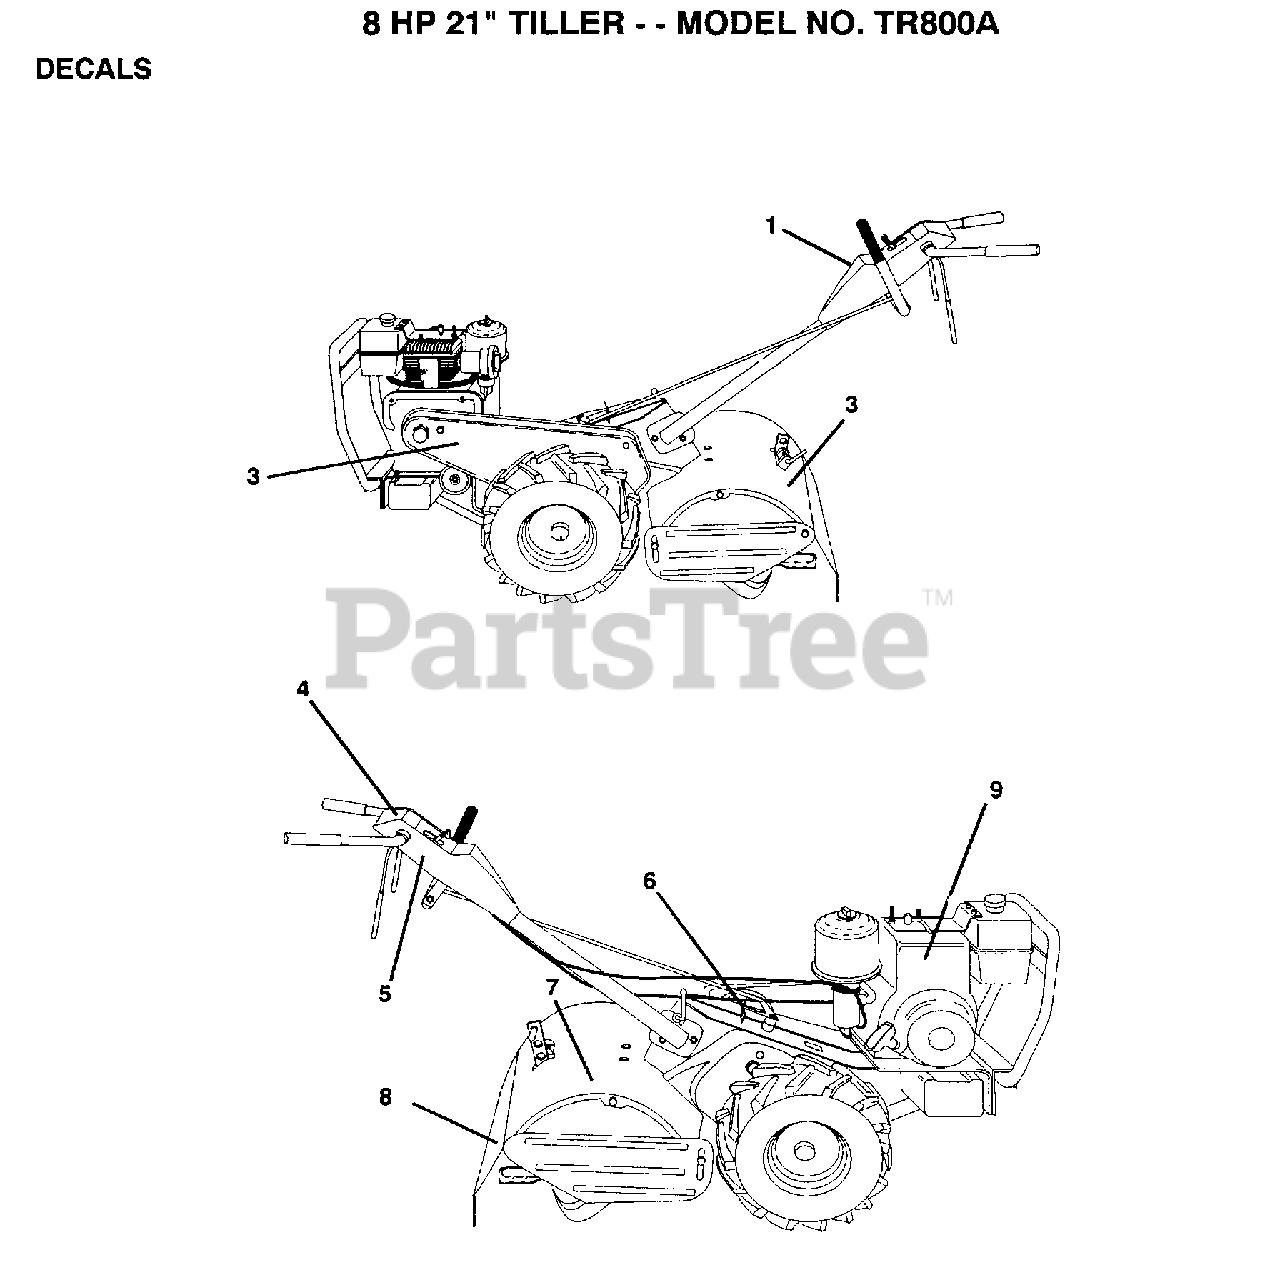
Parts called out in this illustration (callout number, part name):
1	DECAL.PNL.CONTROL
2	DECAL.SHLD.TINE
3	DECAL.GRD.BELT
4	DECAL.INST.PNL.CT
5	DECAL TI
6	DECAL.SHIFT.IND.
8	DECAL TI
9	DECAL, BRIGGS & STRATTON
